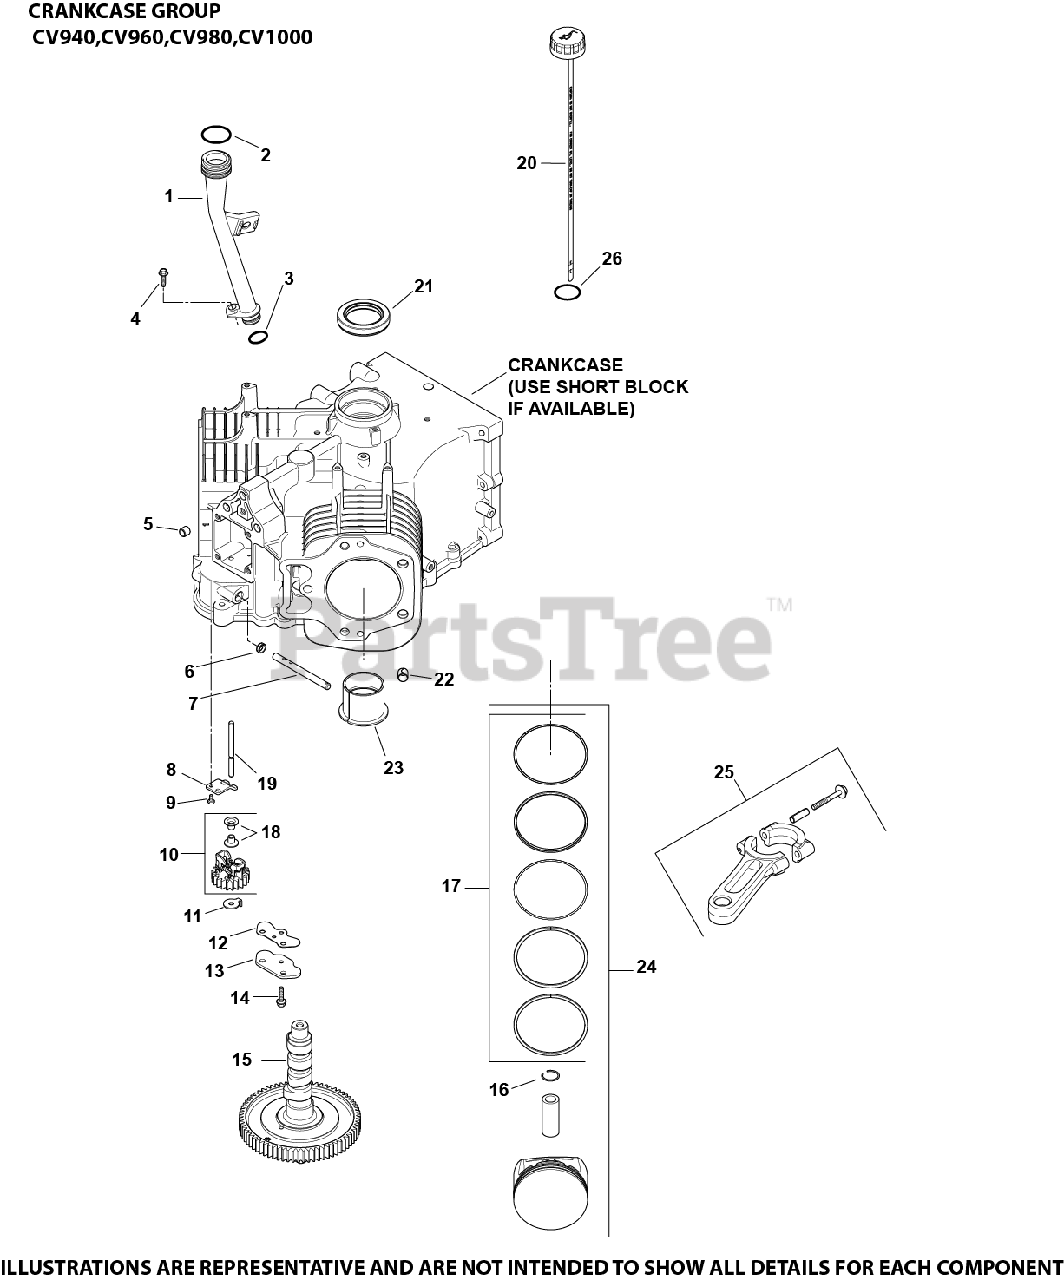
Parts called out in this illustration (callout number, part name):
1	KIT,OIL FILL TUBE
2	O-RING, UPPER OIL FILL TUBE
4	SCREW, FLG THD FRM M5X.8X20-(#25086399S)
6	SEAL, GOVERNOR CROSS SHAFT
7	SHAFT, GOVERNOR CROSS
8	YOKE, GOVERNOR
9	SCREW, HEX HEAD POLY-LOK -USE 25 086 143
10	GOVERNOR GEAR ASSEMBLY USE 25 310 09-S
11	TAB, LOCKING
12	GASKET, LIFTER FEED COVER
13	KIT, COVER, LIFTER FEED
14	SCREW, HVY FLG M5X0.8X20
15	KIT, CAMSHAFT USE 62 010 12-S
16	RETAINER, PISTON PIN
17	RING, SET PISTON (STD)
18	PIN, GOVERNOR REGULATING
19	SHAFT, GOVERNOR GEAR
20	DIPSTICK ASSEMBLY
21	SEAL, OIL
22	PIN, LOCATING
24	KIT, PISTON (STD) (See Kohler Note)
24	KIT, PISTON ASSEMBLY (.25)
24	KIT, PISTON ASSEMBLY (.50)
25	CONNECTING ROD ASSEMBLY
26	O-RING, DIPSTICK
